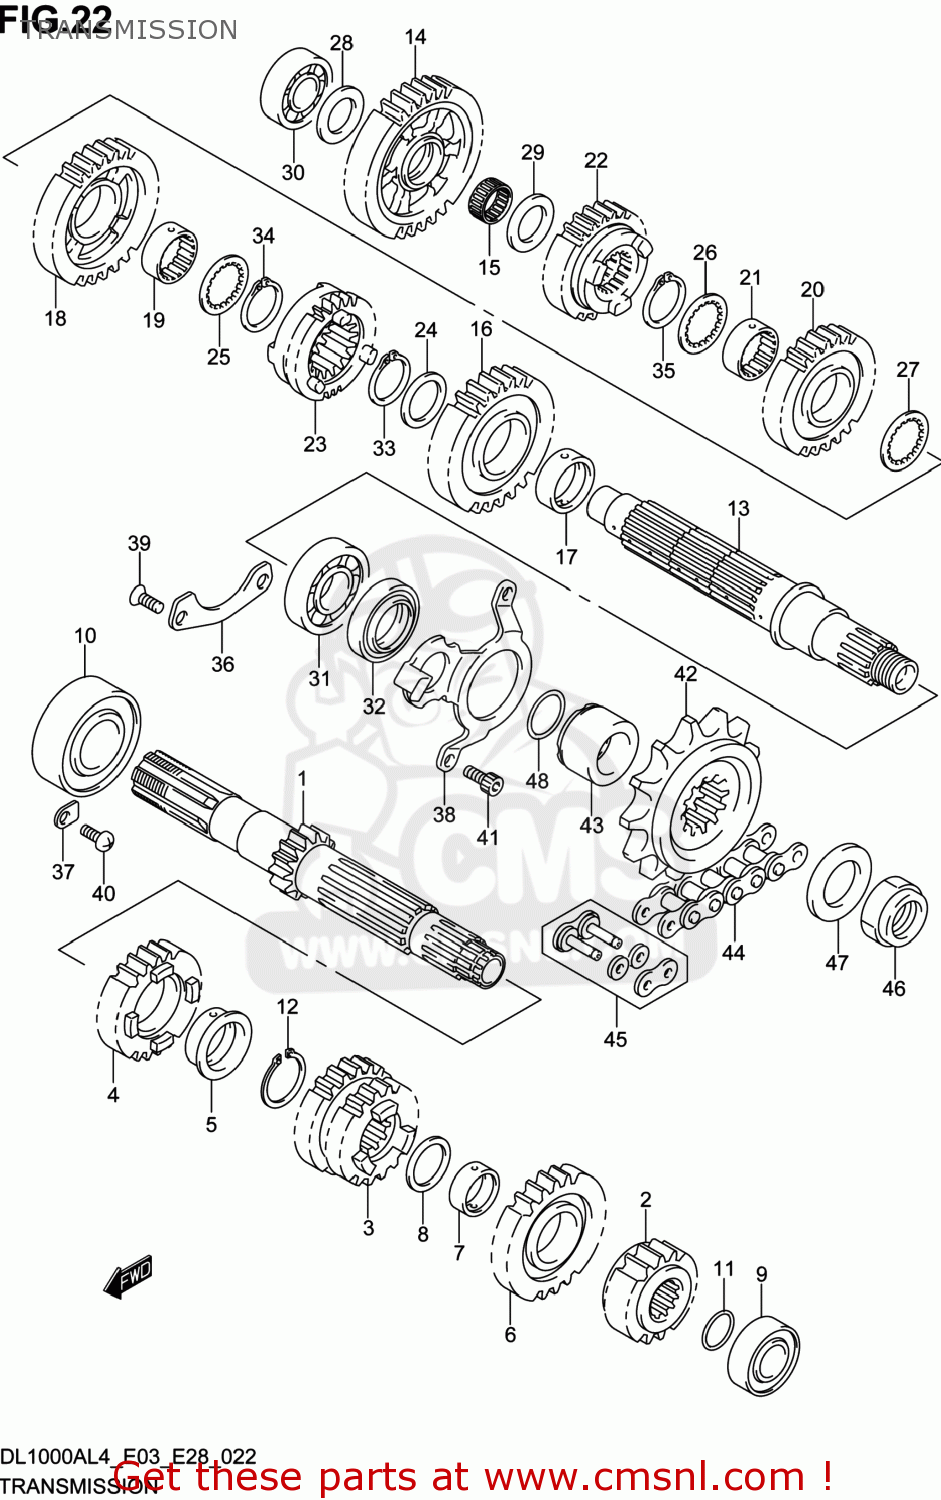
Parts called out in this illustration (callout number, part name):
1	SHAFT,COUNTER (NT:12)
2	GEAR,2ND DRIVE(NT:15)
3	GEAR,3RD & 4TH DRIVE(NT:18/22)
4	GEAR,5TH DRIVE(NT:23)
5	BUSH,5TH DRIVE GEAR
6	GEAR,6TH DRIVE(NT:24)
7	BUSH,6TH DRIVE GEAR
8	SHIM(22X30X1)
9	BEARING(20X47X14)
10	BEARING(25X62X17)
11	O RING(D:1.9,ID:16.6)
12	CIRCLIP
13	SHAFT,DRIVE
14	GEAR,1ST DRIVEN
15	BEARING(22X26X11)
16	GEAR,2ND DRIVEN(NT:29)
17	BUSH,2ND DRIVEN GEAR
18	GEAR,3RD DRIVEN(NT:27)
19	BUSH,3RD DRIVEN GEAR
20	GEAR,4TH DRIVEN(NT:27)
21	BUSH,3RD DRIVEN GEAR
22	GEAR,5TH DRIVEN(NT:25)
23	GEAR,6TH DRIVEN(NT:24)
24	WASHER(27X36X1)
25	WASHER,3RD & 4TH DRIVEN
26	WASHER,3RD & 4TH DRIVEN
27	WASHER,3RD & 4TH DRIVEN GEAR
28	SHIM(20X34X1)
29	SHIM(22X34X1)
30	BEARING(20X52X15)
31	BEARING(28X68X18)
32	SEAL,OIL(38X52X8)
33	CIRCLIP
34	CIRCLIP
35	CIRCLIP
36	RETAINER,DRIVE SHAFT BEARING
37	RETAINER
38	RETAINER,DRIVE SHAFT OIL SEAL
39	SCREW(6X12)
40	SCREW
41	BOLT
42	SPROCKET,ENGINE(17T)
43	SPACER,ENGINE SPROCKET
44	CHAIN,DRIVE
45	JOINT SET,DRIVE CHAIN
46	NUT
47	WASHER(25X41X3)
48	O RING(D:2.4,ID:23.7)
